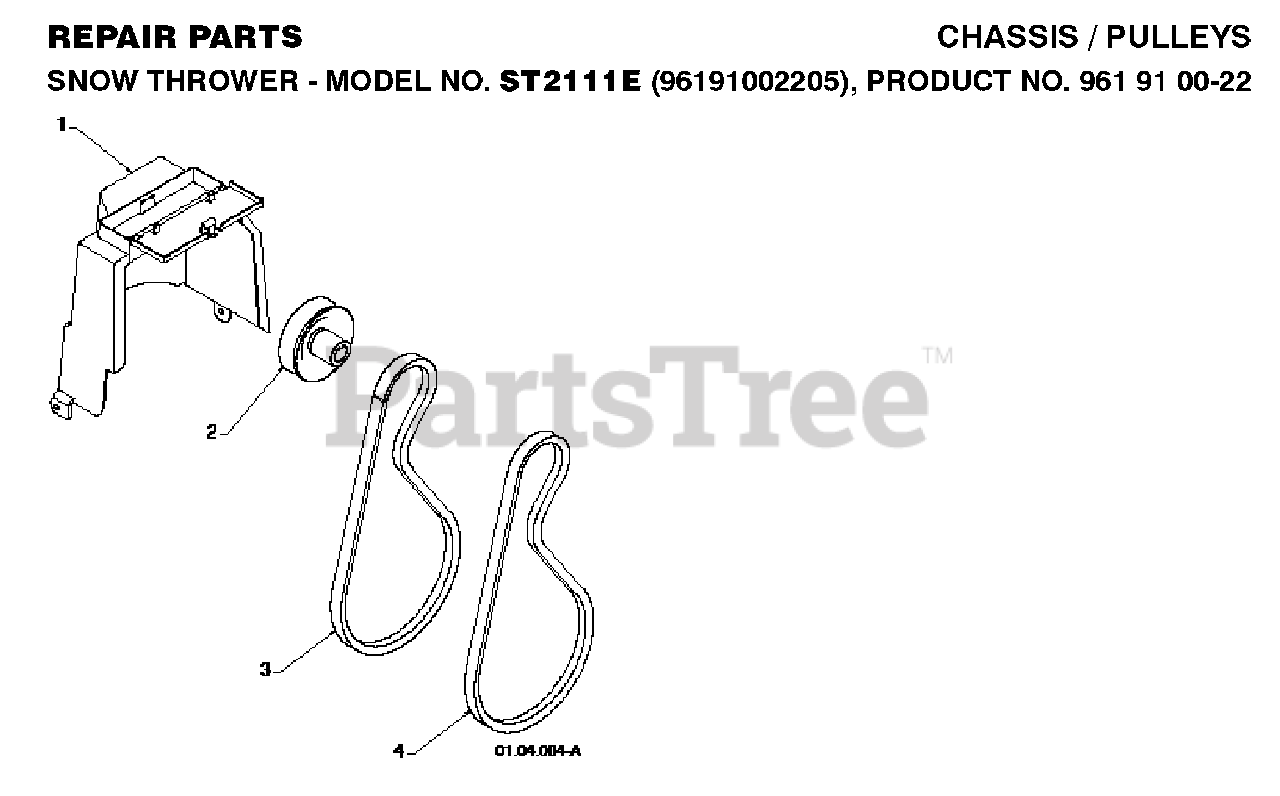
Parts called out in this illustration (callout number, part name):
1	COVER.BELT.HS
2	PULLEY
3	V-BELT.TRACTION
4	BELT-V.IMPELLER.HS
